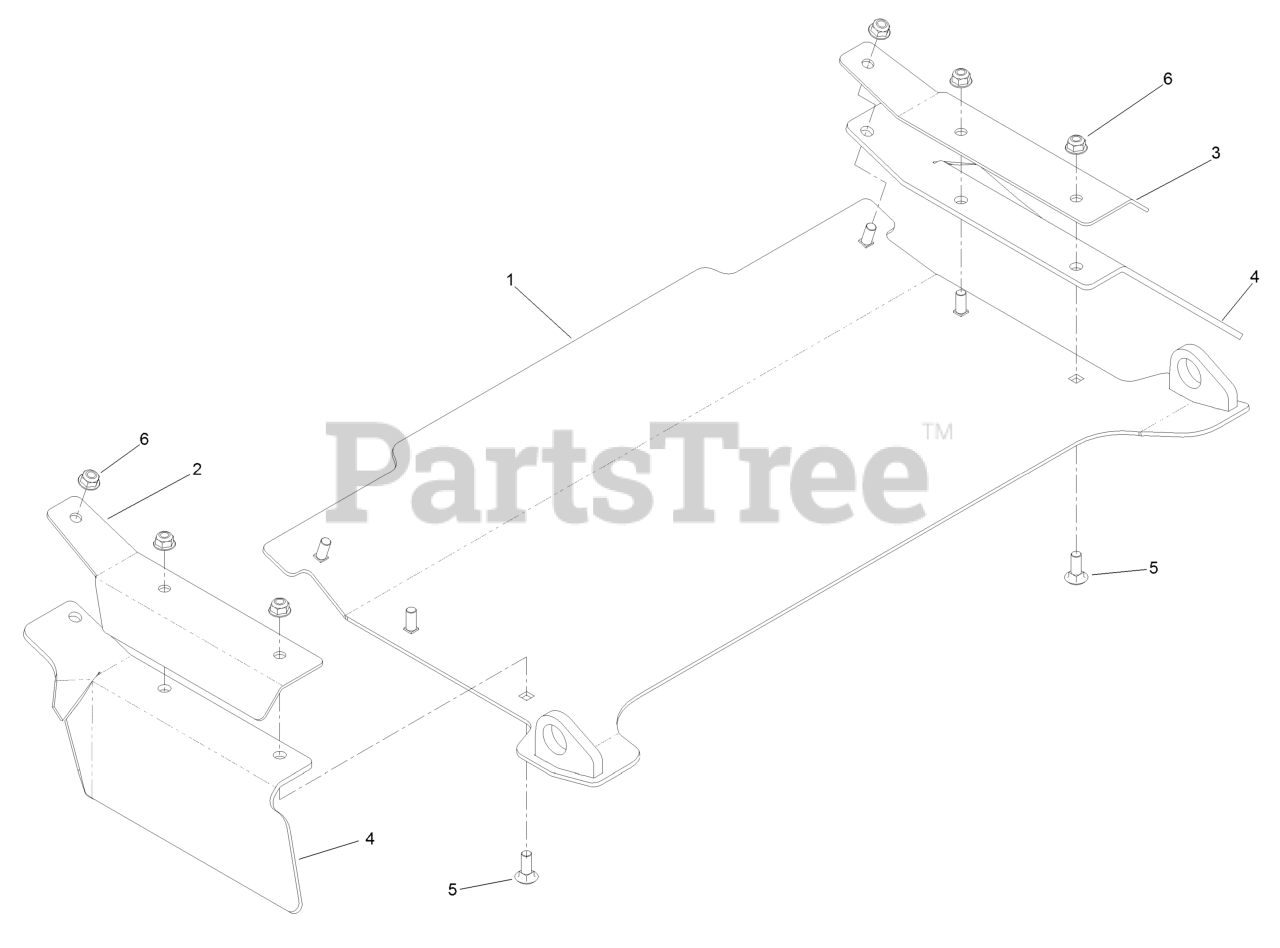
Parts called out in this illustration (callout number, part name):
1	DISCHARGE TUNNEL ASM
2	BRACKET-FLAP, LH
3	BRACKET-FLAP, RH
4	FLAP-RUBBER
5	SCREW-CARR
6	NUT-HF, NI
